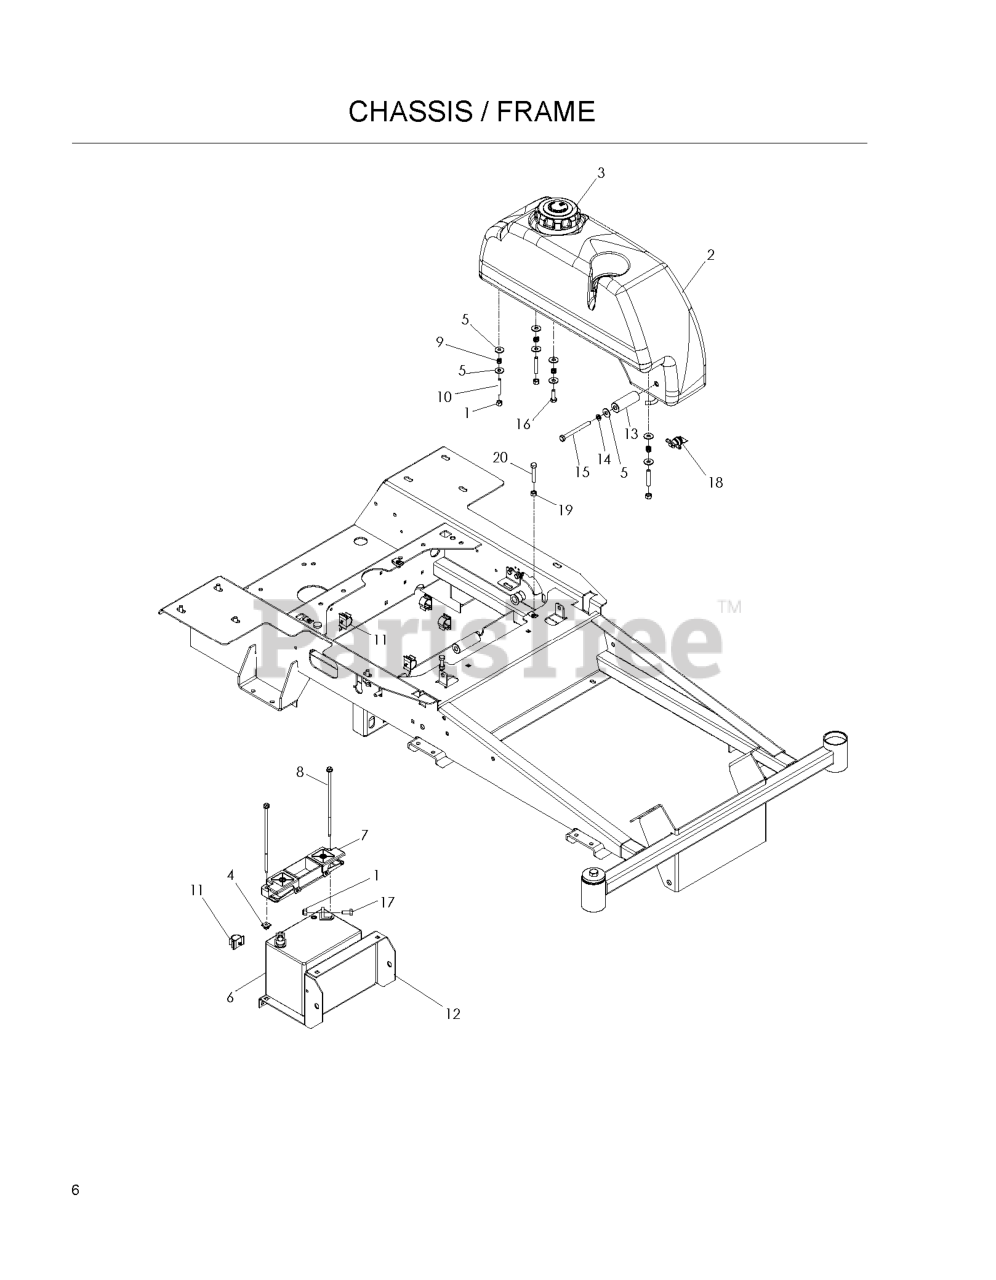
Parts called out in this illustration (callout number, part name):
1	NUT 5/16 NYLOC
2	LEFT TANK W/CUP HOLDER
3	FUEL CAP ANTI-SPLASH
4	PUSH NUT-NYLON
5	WASHER 5/16 FLAT
6	BATTERY, 12 V 330 AMP
7	BATTERY HOLD DOWN
8	BOLT - 1/4-20 X 7.5
10	STUD, 5/16C
11	PUSH-MOUNT WIRE CLIP
12	BATTERY TRAY
13	TANK SPACER
14	WASHER.LOCK.HVY.HLCL.SPR.5/16
15	BOLT - HCS 5/16C X 3.5
16	HCS 5/16C X 1
17	HCS 5/16C X 3/4
18	FUEL VALVE
19	NUT 5/16C HEX
20	HCS 5/16-18X1-3/4 TPBLT
